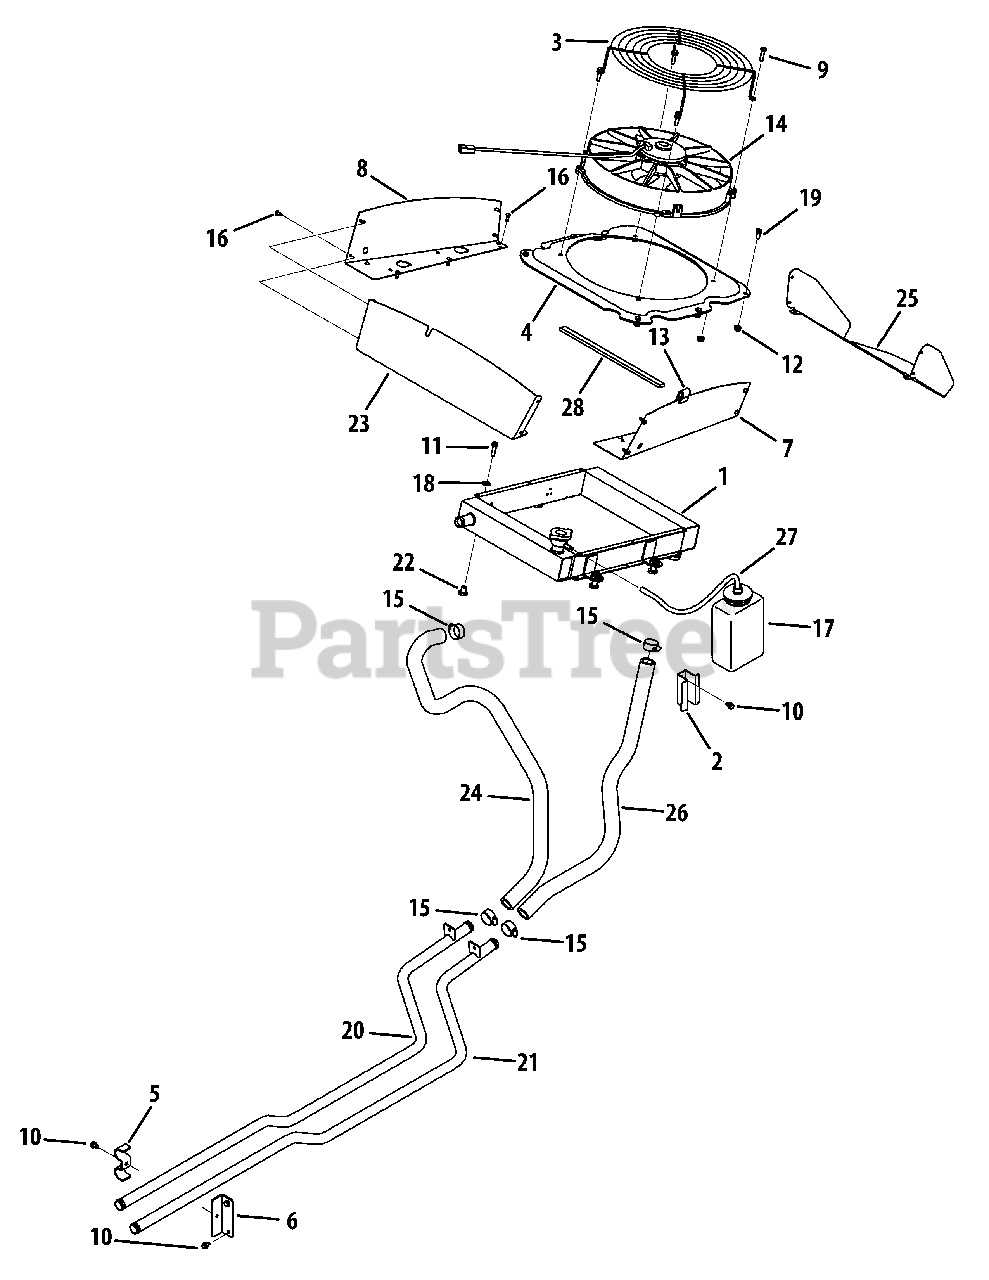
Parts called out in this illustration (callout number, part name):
1	Radiator Asm, zin Core
3	Guard, fan
4	Shrd, Fan, Mount
9	Hhcs, 1/4-20, 1.00, gr5
10	Scr, tt, 1/4-20, 0.500, hxindwsh
11	Scr, tt, 1/4-20, 1.000, hxindwsh
12	Nut, flglk, 1/4-20, grf, nylon
13	Heat Baffle Seal
14	Fan, electric, 12v
15	Clamp, hose, adj
16	Pop Rivet 3/16 Dia x .450, sty1
17	Cntnr, over Flow, coolant
18	Wash, flat, .28 x .74 x .063
19	Scr., 1/4-20 x .620
22	Spcr, Step
24	Hose, rdtr, frt 4x4
26	Hose, rdtr, frt 4x4
27	Tube, overflow, rdtr
28	Tape, .625 Wide x .25 Thk Foam
